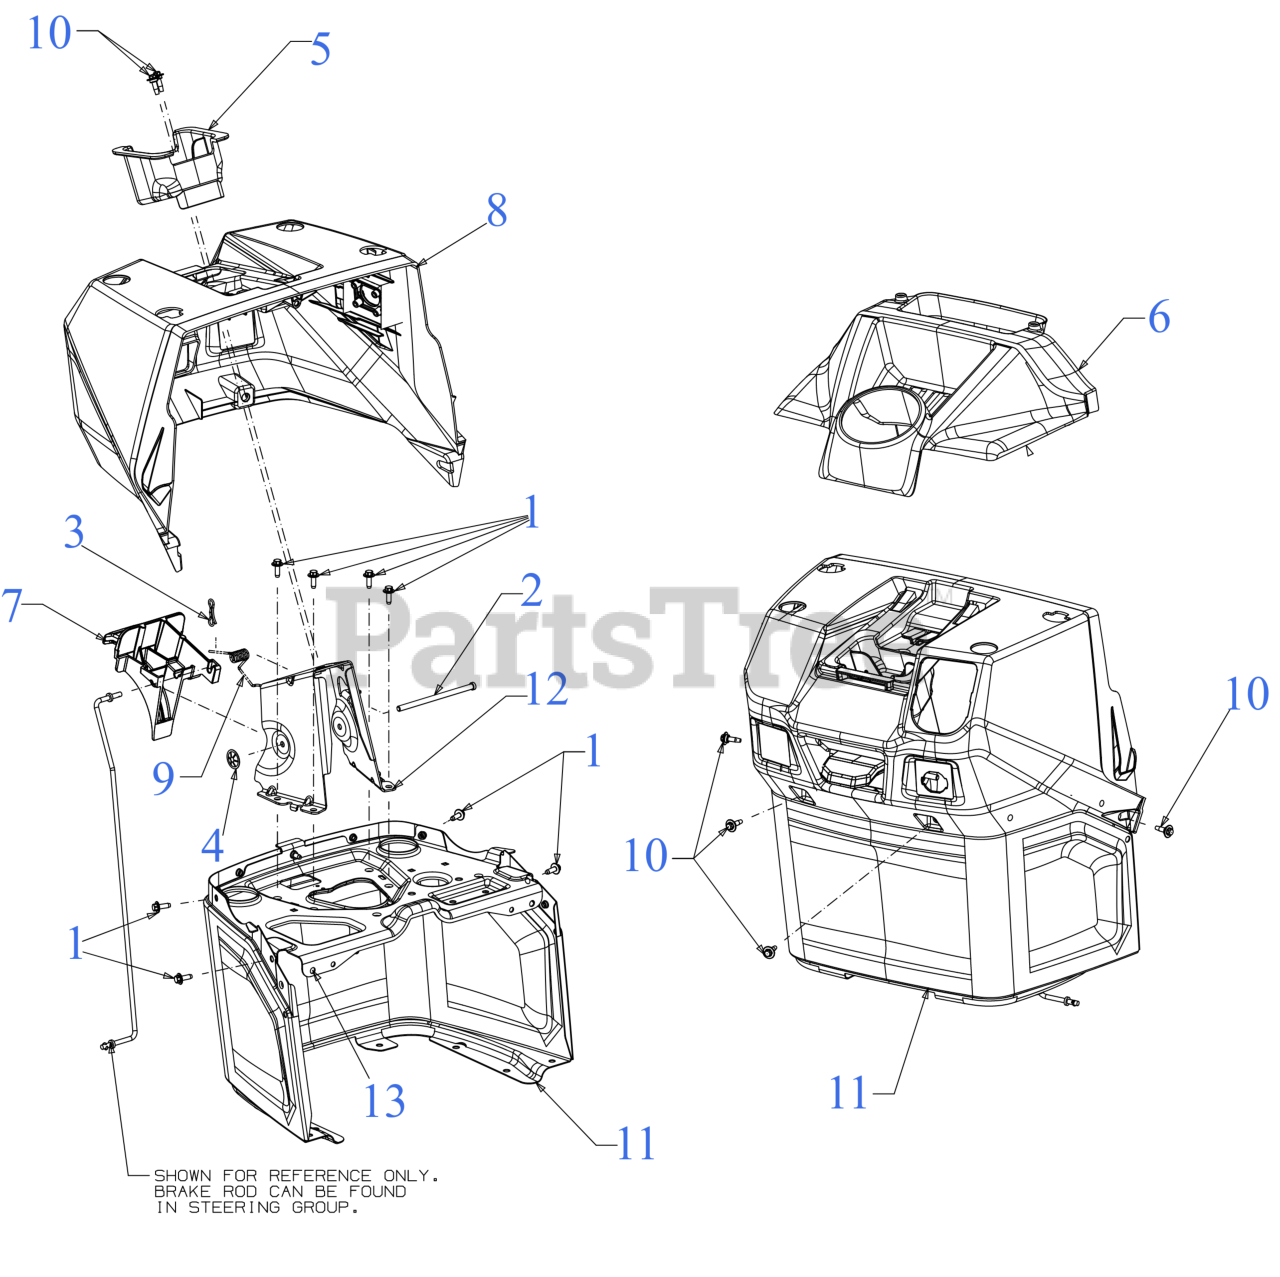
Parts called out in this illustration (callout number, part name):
1	SCREW M6-1 x .625
2	HINGE PIN .25 x 4.50
3	BOW TIE COTTER PIN 1/4-5/16
4	PUSH ON NUT
5	STEERING SHAFT BEARING
6	UPPER DASH CAP
7	BRAKE LEVER
8	DASH (UPPER)
9	TORSION SPRING .330 ID
10	SHOULDER SCREW M6-1 .368 X.115
13	DASH/FUEL TANK PLATE
